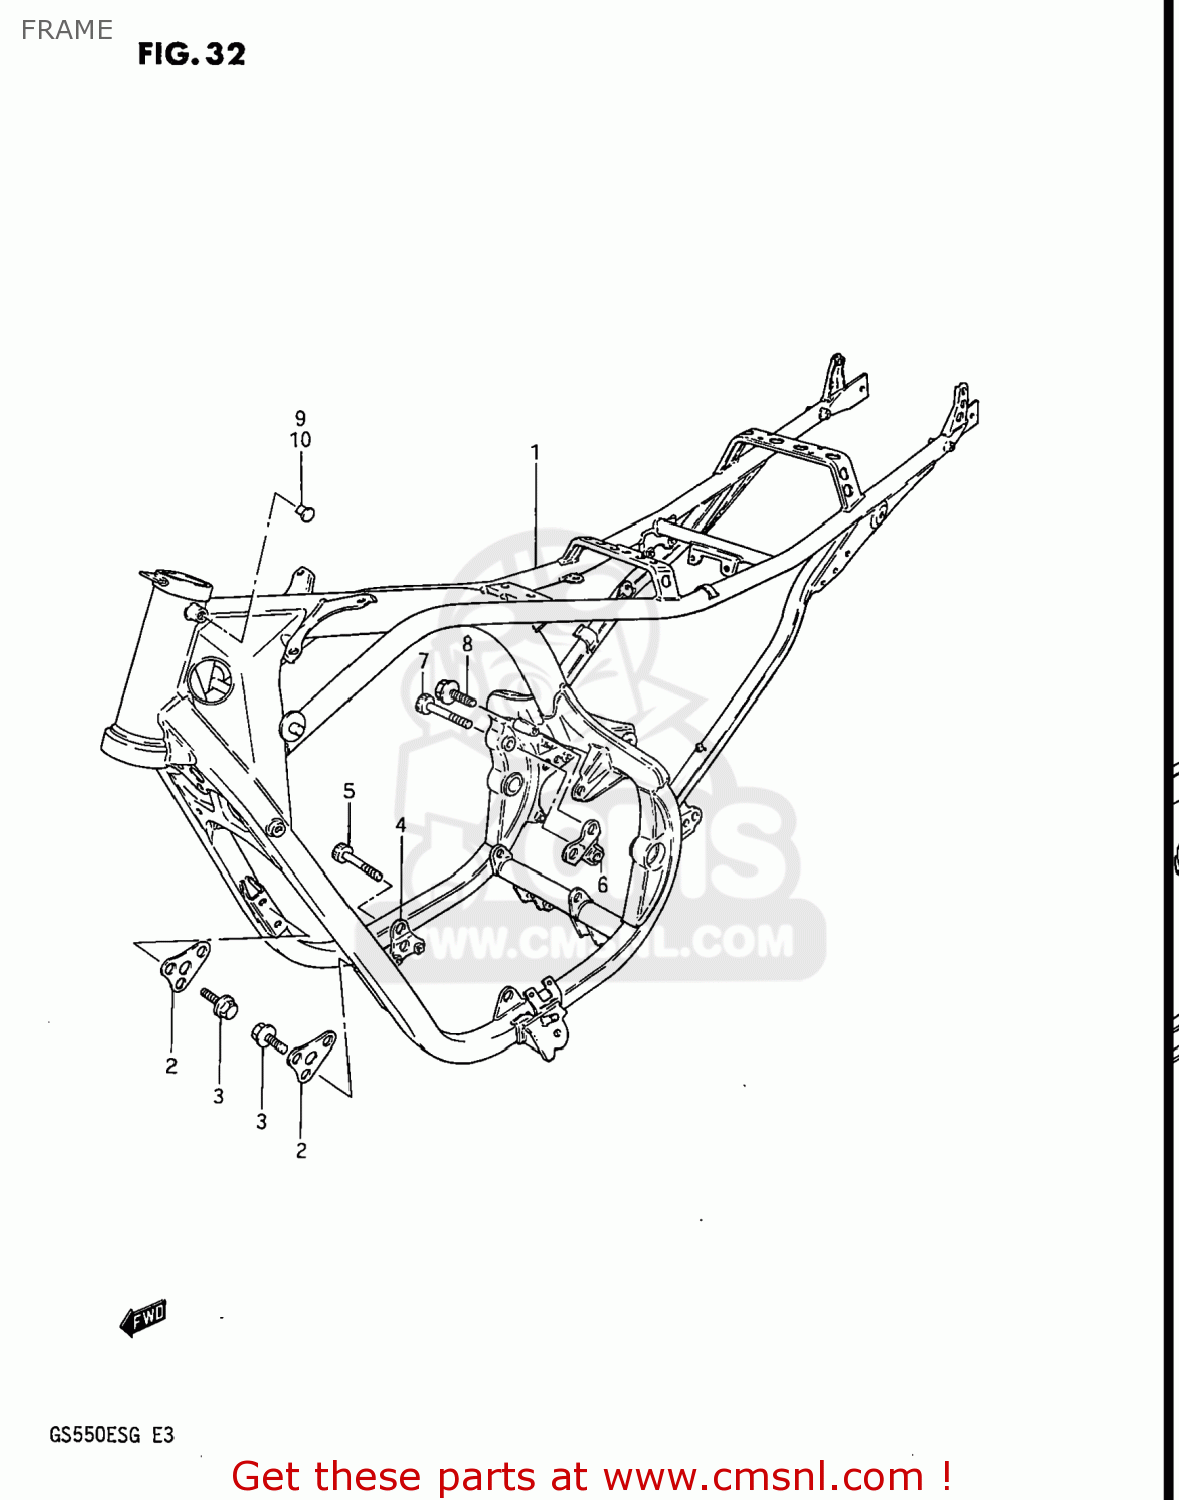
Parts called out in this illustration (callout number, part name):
1	FRAME
2	PLATE,ENGINE MOUNTING NO
3	BOLT 8X16
4	PLATE,ENGINE MOUNTING NO
5	BOLT
6	PLATE,ENGINE MOUNTING NO.4
7	BOLT
8	BOLT 8X16
9	PLUG
10	PLUG
